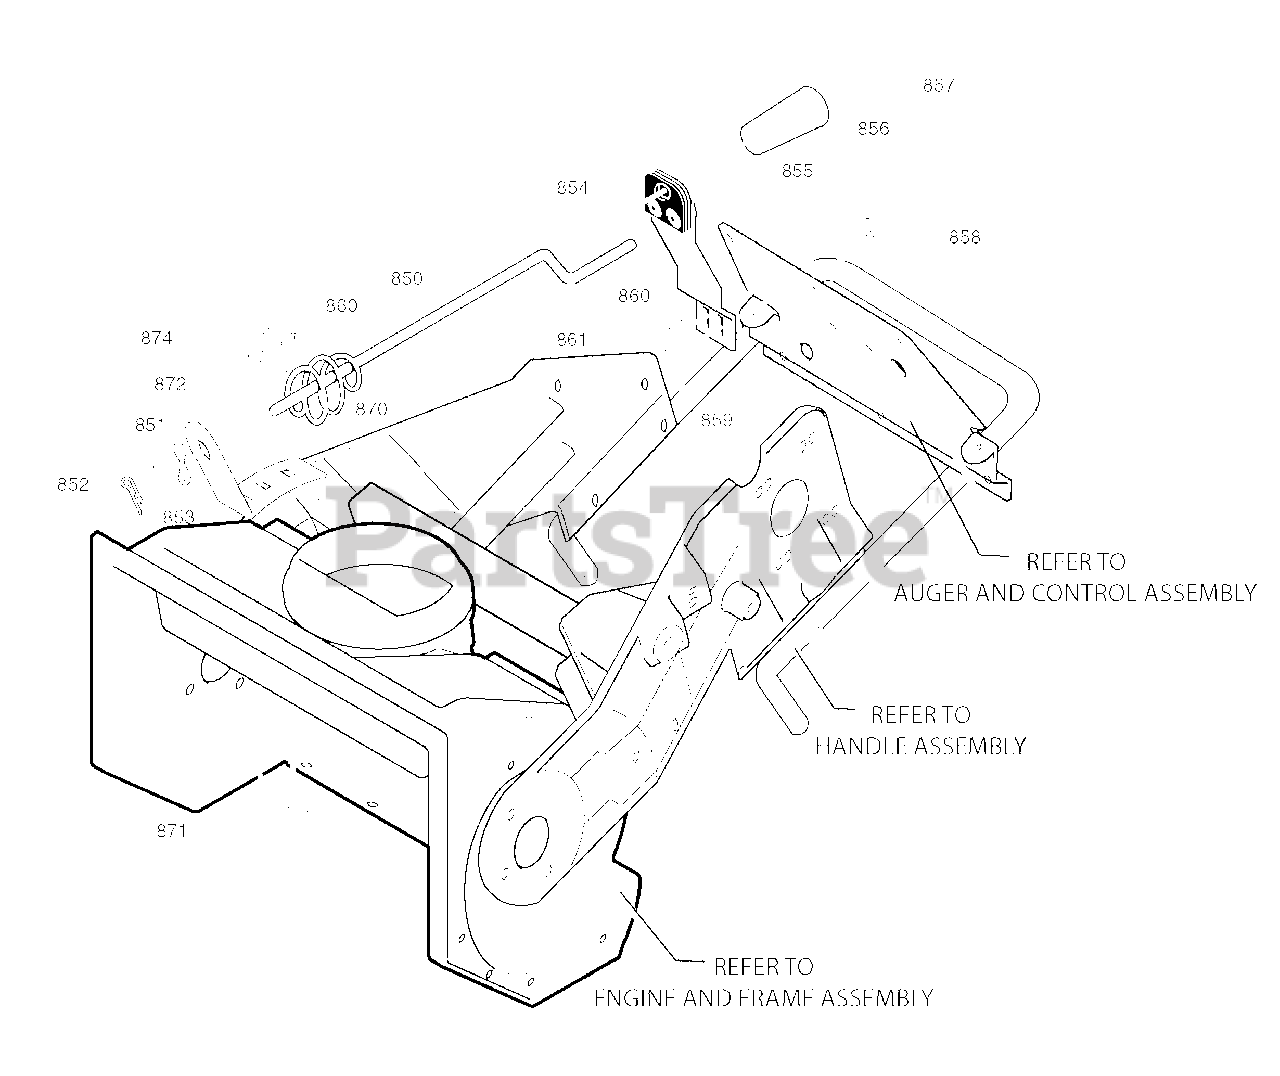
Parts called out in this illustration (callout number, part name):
850	ROD, CHUTE
851	WASHER, Flat, 13/32 x 13/16
852	PIN, Hair
853	WASHER, Curved
854	CHUTE CRANK ASSEMBLY
855	WASHER, Flat, 13/32 x 13/16
856	KNOB, Sleeve
857	NUT, Push, 3/8
858	BOLT, Carriage, 1/4-20 x 5/8
859	WASHER, Flat, 11/32 X 11/16
860	WASHER, Split Lock, 5/16 x 37/64
861	NUT, Hex, 1/4-20
870	BRACKET, Chute Rotate
871	BOLT, Carriage, 5/16-18 x 3/4
872	WASHER, Flat, 11/32 X 11/16
874	NUT, Hex, 5/16-18
